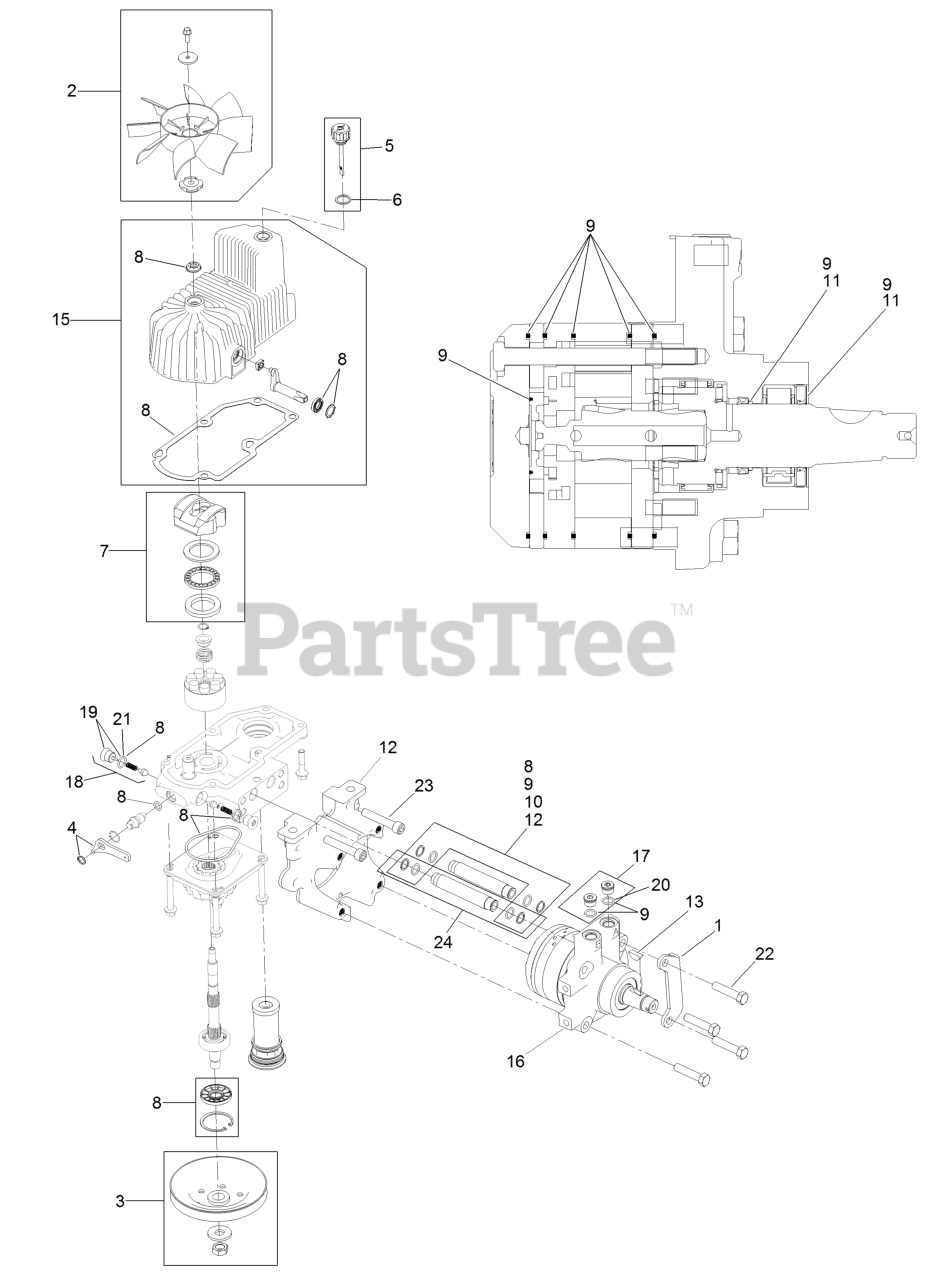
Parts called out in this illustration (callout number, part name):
1	MOUNT-SHOE, HORSE
2	FAN KIT
3	PULLEY KIT
4	HANDLE-BYPASS VALVE, HYDRO
5	DIPSTICK-HYDRO W/GASKET
6	GASKET-DIPSTICK, HYDRO
7	SWASH BLOCK KIT
8	PUMP SEAL KIT
9	MOTOR SEAL KIT
10	TUBE SEAL KIT
11	OUTPUT SHAFT SEAL KIT
12	NOSE CUP-UHT
13	KEY-WOODRUFF
15	HOUSING-HYDRO, RH
16	MOTOR-HYDRAULIC RH 240CC
17	MAGNETIC PLUGS SERVICE KIT
18	CHECK VALVE ASM
19	PLUG-CHECK (W/O-RING)
21	O-RING-CHECK VALVE
22	SCREW HH
23	SCREW-HSH
24	HYDRAULIC TUBE KIT
